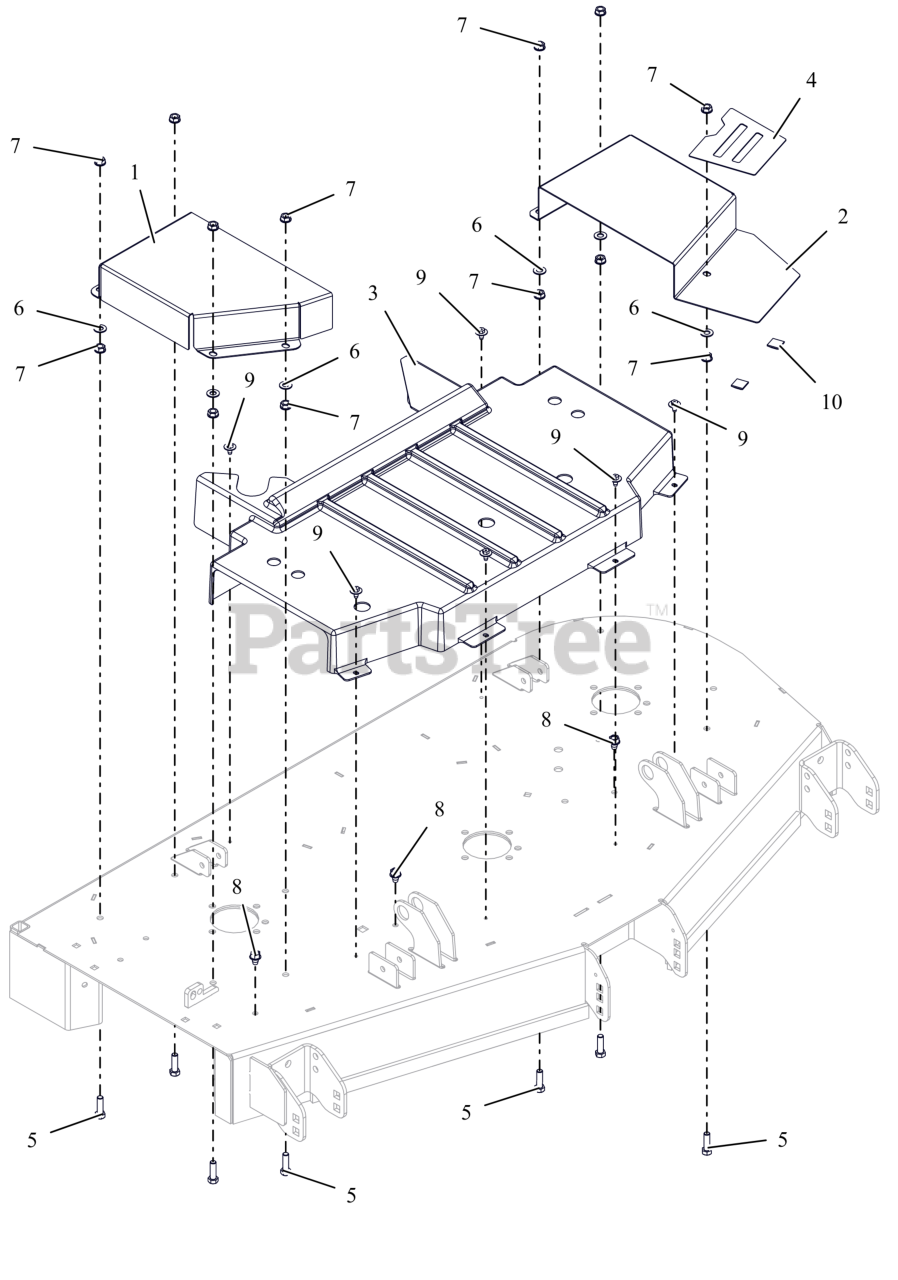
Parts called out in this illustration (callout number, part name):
1	GUARD,BELT 52" RIGHT CE
2	GUARD,BELT 52" LEFT CE
3	GUARD,CENTER,DECK SPINDLE CE
4	GRIP TAPE 52-60 BELT COVER
5	BLT, HEX .38-16X1.25 G5 ZCC
6	WSHR,FLT .406X.812X.065 ZCC
7	NUT, SPNLK-FLG .38-16 G5 ZCC
8	SCR,TAP .375-16X.50 HWH TR ZCC
9	SCR, TAP .25-20X.50 LG HWH ZCC
